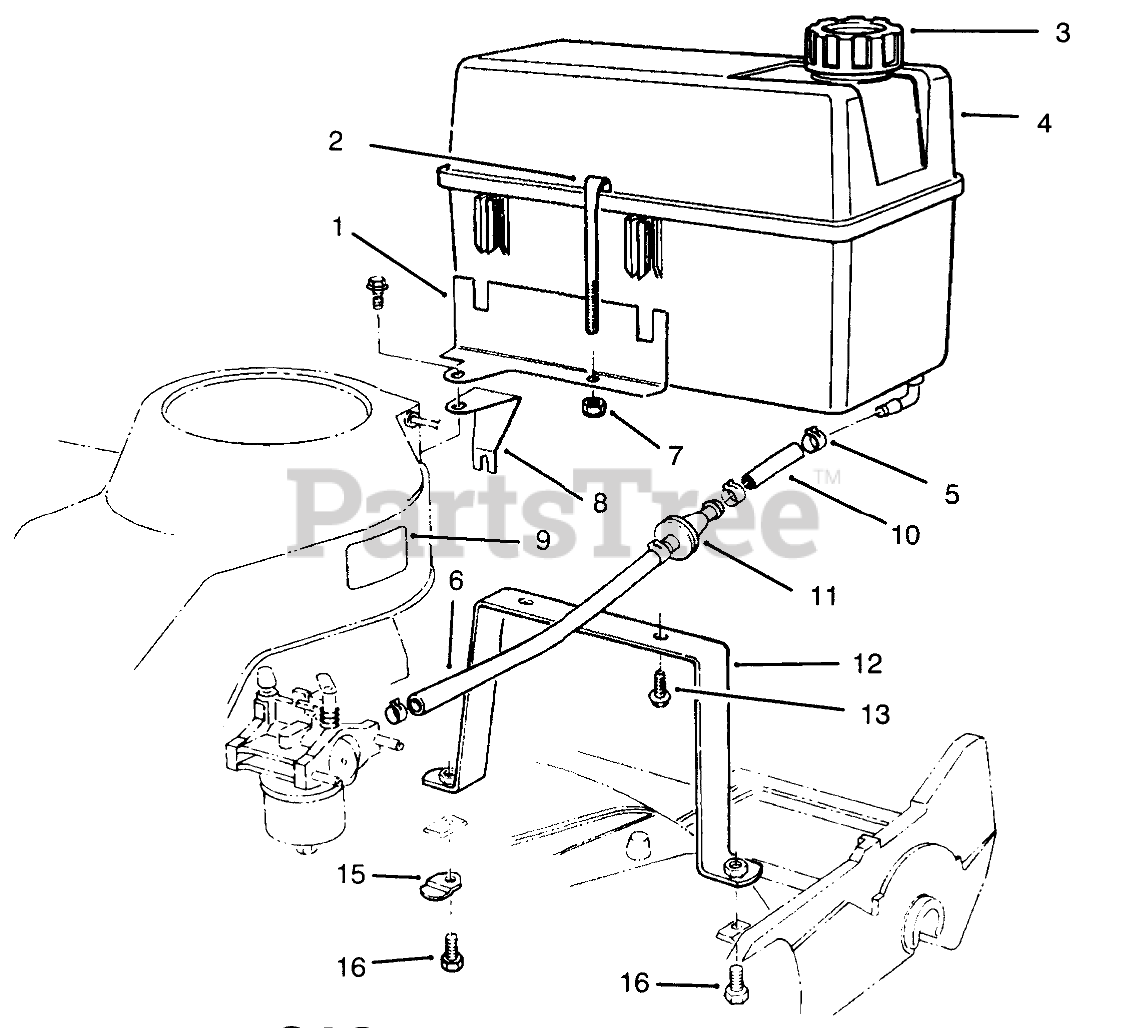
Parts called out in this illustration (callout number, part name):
1	Bracket Tank
2	RETAINER - FUEL TANK
3	GAS CAP ASM
4	Tank-Gas
5	CLAMP-FUEL LINE
6	HOSE-FUEL
7	NUT-LOCK, NI
8	Support-Bracket
9	DECAL - FUEL
10	LINE-GAS
11	FILTER-FUEL
12	Base-Tank
13	SCREW-HWH
15	SHIELD-RETAINER
16	SCREW-HH
